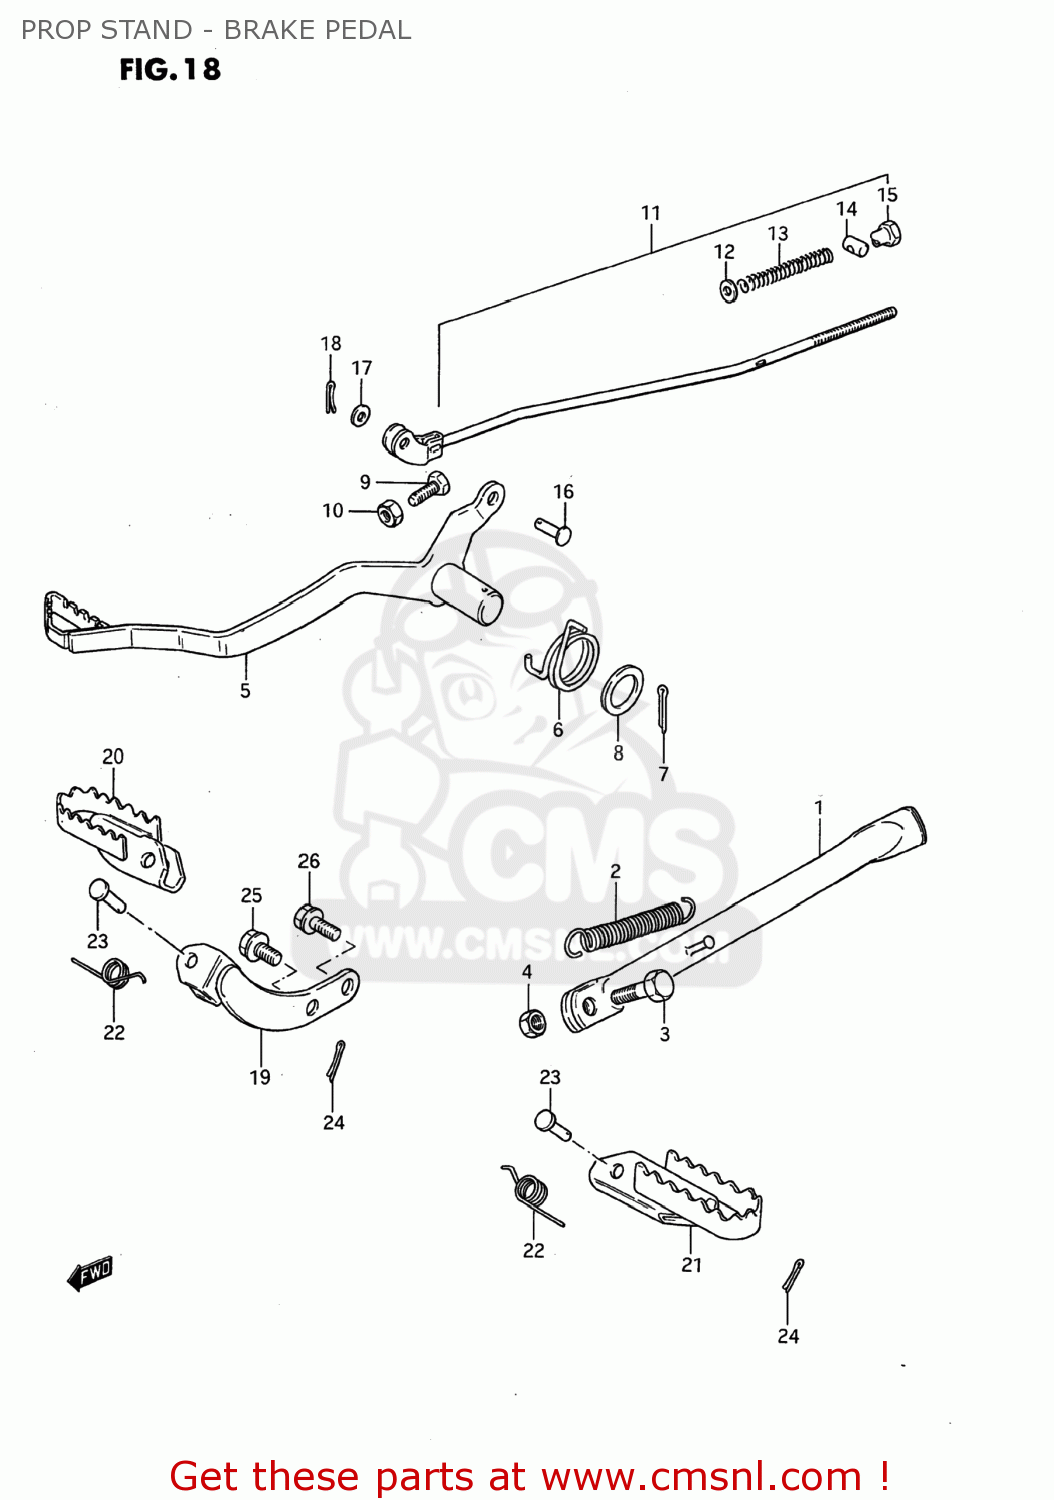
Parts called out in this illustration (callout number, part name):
1	STAND,SIDE
2	SPRING
3	BOLT
4	NUT
5	PEDAL,BRAKE
6	SPRING
7	COTTER PIN
8	WASHER(15.5X26X2.3)
9	BOLT(6X23)
10	NUT
11	ROD ASSY,RR BRAKE
12	WASHER
13	SPRING
14	PIN(11X18)
15	NUT (6MM)
16	PIN(L:13.5)
17	WASHER
18	PIN 20X20
19	BAR,FRONT FOOTREST
20	FOOTREST,FR,R
21	FOOTREST,FR,L
22	SPRING
23	PIN
24	PIN 20X20
25	BOLT
26	BOLT
